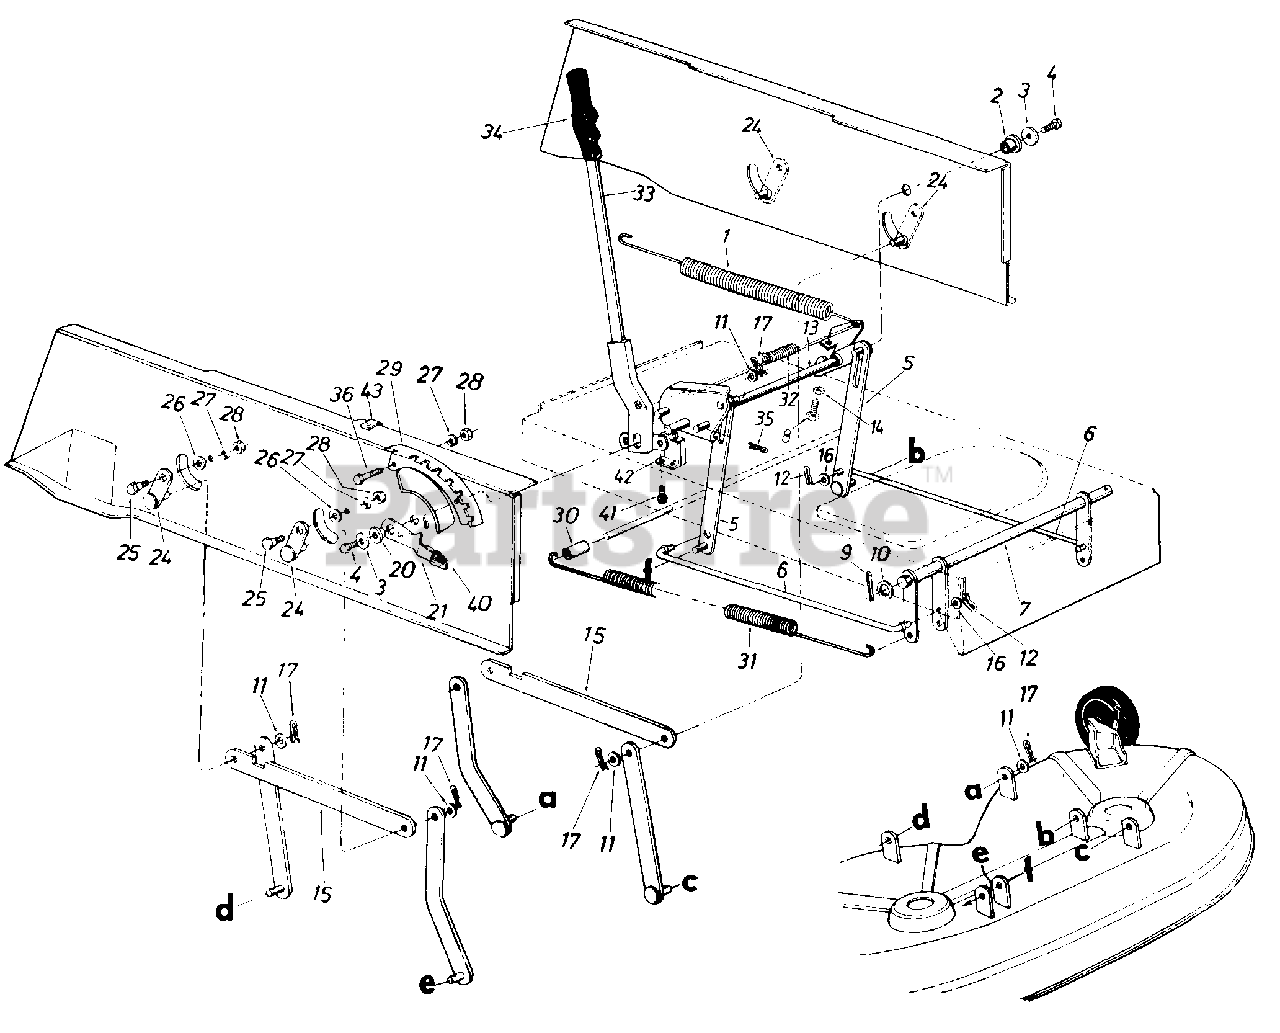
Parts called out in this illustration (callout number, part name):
1	Extension Spring 11" Lg.
2	Flange Bearing .634" I.D.
3	Fl-Wash. .344" I.D. x 1.125"
4	Hex Wash. Hd. 5/16-18 x .62" Lg.
5	Link Deck Lift Ass'y.
6	Stabilizer Rod
7	Stabilizer Shaft Ass'y.
8	Hex Tap Scr. 5/16-18 x 1"
9	Cotter Pin 118" Dia. x 11/4"
10	Fl-Wash. .635" I.D. x 1.12"
11	Fl-Wash. .531" I.D. x .940"
12	Cotter Pin 3/32" Dia.
13	Lift Shaft Ass'y.
14	Hex Jam Nut 5/16-18 Thd.
15	Connecting Rod
16	Fl-Wash. .385" I.D. x .62"
17	Inter. Cotter Pin 1/2" Dia.
20	Flange Brg. .630" I.D.
21	Deck Lift Down Stop
24	Pivot Link Ass'y.
25	Shld. Bolt .437" Dia. x .180" Lg. (5/16-18)
26	Fl-Wash. .344" I.D. x .62"
27	L-Wash. 5/16" I.D.
28	Hex Nut 5/16-18 Thd.
29	Index Brkt.
30	Spacer .523" I.D. x .640" O.D. x 1.95" Lg.
31	Ext. Spring 13.25" Lg.
32	Ext. Spring
33	Lift Handle Ass'y.
34	Grip
35	Intern. Cotter Pin 3/8" Dia.
36	Hex Bolt 5/16-18 x .75"
40	Knob
41	Hex AB-Tap Scr. #10 x .501"
42	Safety Switch
43	Clamp
